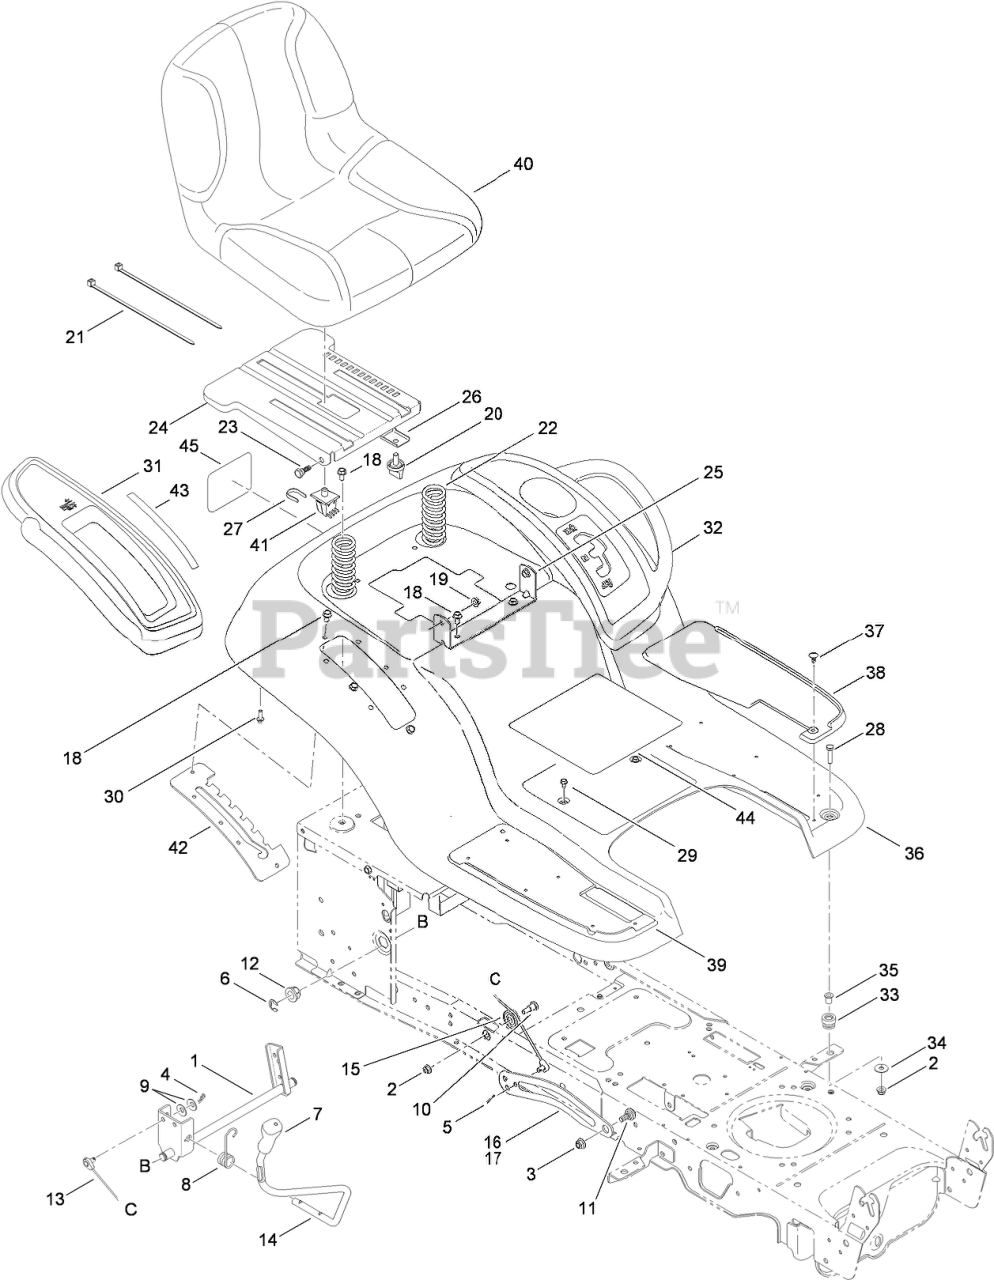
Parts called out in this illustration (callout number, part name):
1	LIFT SHAFT ASM
2	NUT-LOCK, FLANGE
3	NUT-LOCK, FLANGE
4	PIN-COTTER
5	PIN-COTTER
6	RING-E
7	GRIP-HANDLE
8	SPRING-TORSION
9	WASHER-SPRING
10	BOLT-SHOULDER
11	BOLT-SHOULDER
12	BEARING-FLANGE
13	CABLE-LIFT
14	HANDLE-LIFT
15	PULLEY-CABLE
16	ARM-LIFT, RH
17	ARM-LIFT, LH
18	SCREW-TAP
19	NUT-LOCK, FLANGE
21	TIE-CABLE
22	SPRING-COMPRESSION
23	BOLT-SHOULDER
24	BRACKET-MOUNT, SEAT
25	BRACKET-PIVOT, SEAT
26	BRACKET-KNOB, ADJUSTMENT
27	CLIP-RETENSION
28	SCREW-HH
29	SCREW-HWHTF
30	SCREW-TAP
31	COVER-FENDER, RH
32	COVER-FENDER, LH (W/CUPHOLDER)
33	GROMMET
34	WASHER-FLAT
35	SPACER
36	FENDER
37	CLIP-RATCHET
38	PAD-FOOT, LH
39	PAD-FOOT, RH
40	SEAT-HIGH
41	SWITCH-SEAT
42	BRACKET-LIFT
43	DECAL-HOC AND PTO
44	DECAL-SAFETY
45	DECAL-TORO
